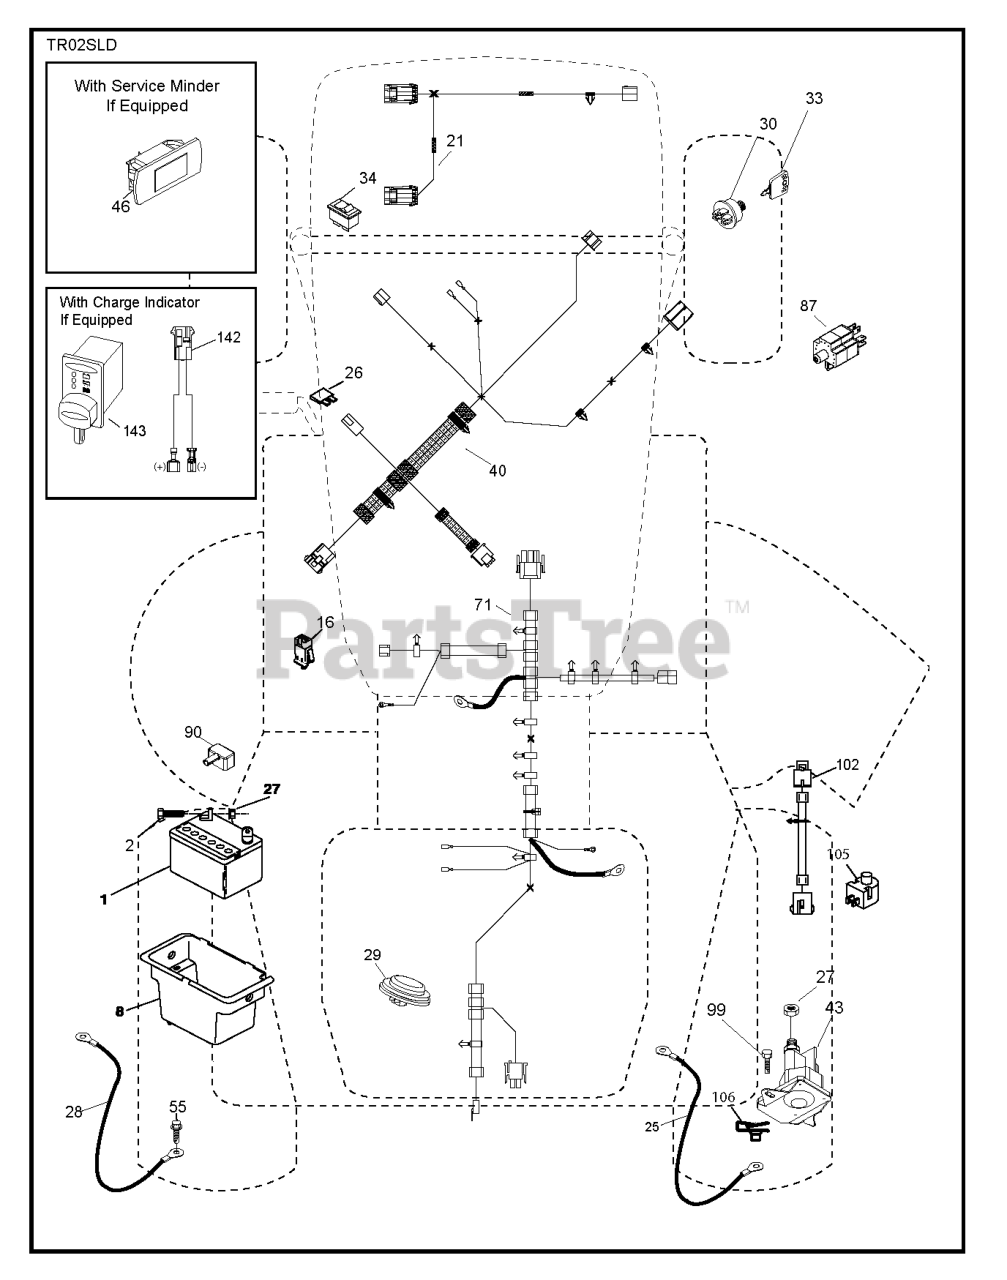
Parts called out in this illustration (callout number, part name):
1	Battery 12 Volt 25 Amp
2	BOLT.HEX.1/4.X.3/4.DICHROMATE
8	BOX.BATTERY.MNT.REAR.L
16	SWITCH INTERLOOK PUSH-IN
21	HARNESS LIGHT ASSY TRACTOR,
25	CABLE.BATT.RED.8GA.17
26	FUSE 20AMP
27	NUT
28	CABLE.GROUND.REAR.BATTERY.8G
29	SWITCH.SEAT.DELTA.OPC.
30	SWITCH.IGN.DELTA.W.LGH.ROS
33	KEY.CHAIN.BLISTER.PACK.GEN.INT
40	HARNESS.TEX.DASH.MAN.REAR BATT
43	SOLENOID.STARTER.BRASS.PLUNGER
46	GUAGE.SRVCMNDR.HRMTR.
55	SCREW 5/16"
71	HARNESS.CHASSIS.RRBATT.RDYSTRT
87	SWITCH.INTRLCK.CLUTCH.
90	COVER.TERMINAL.BATTERY
99	SCREW HEXWSHR 1/4-20X3/4
102	HARNESS PIGTAIL PCH TEX ROS
105	REVERSE SWITCH
106	1/4-20 U NUT
